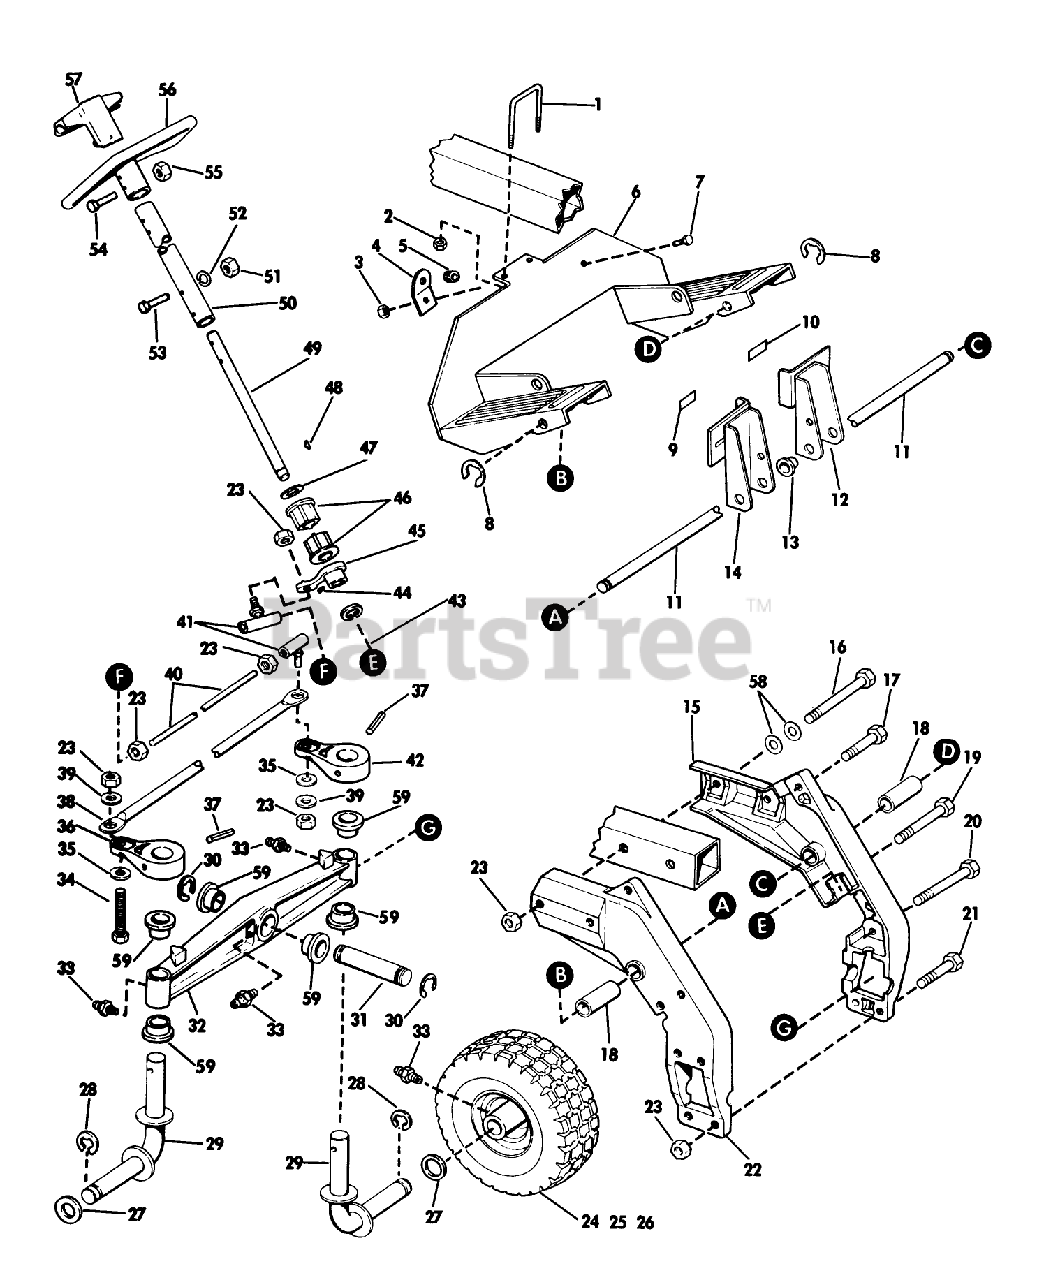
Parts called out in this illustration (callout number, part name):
5	Bushing
33	Grease Fitting
34	Screw-King Pin
55	Nut-Steering Shaft
